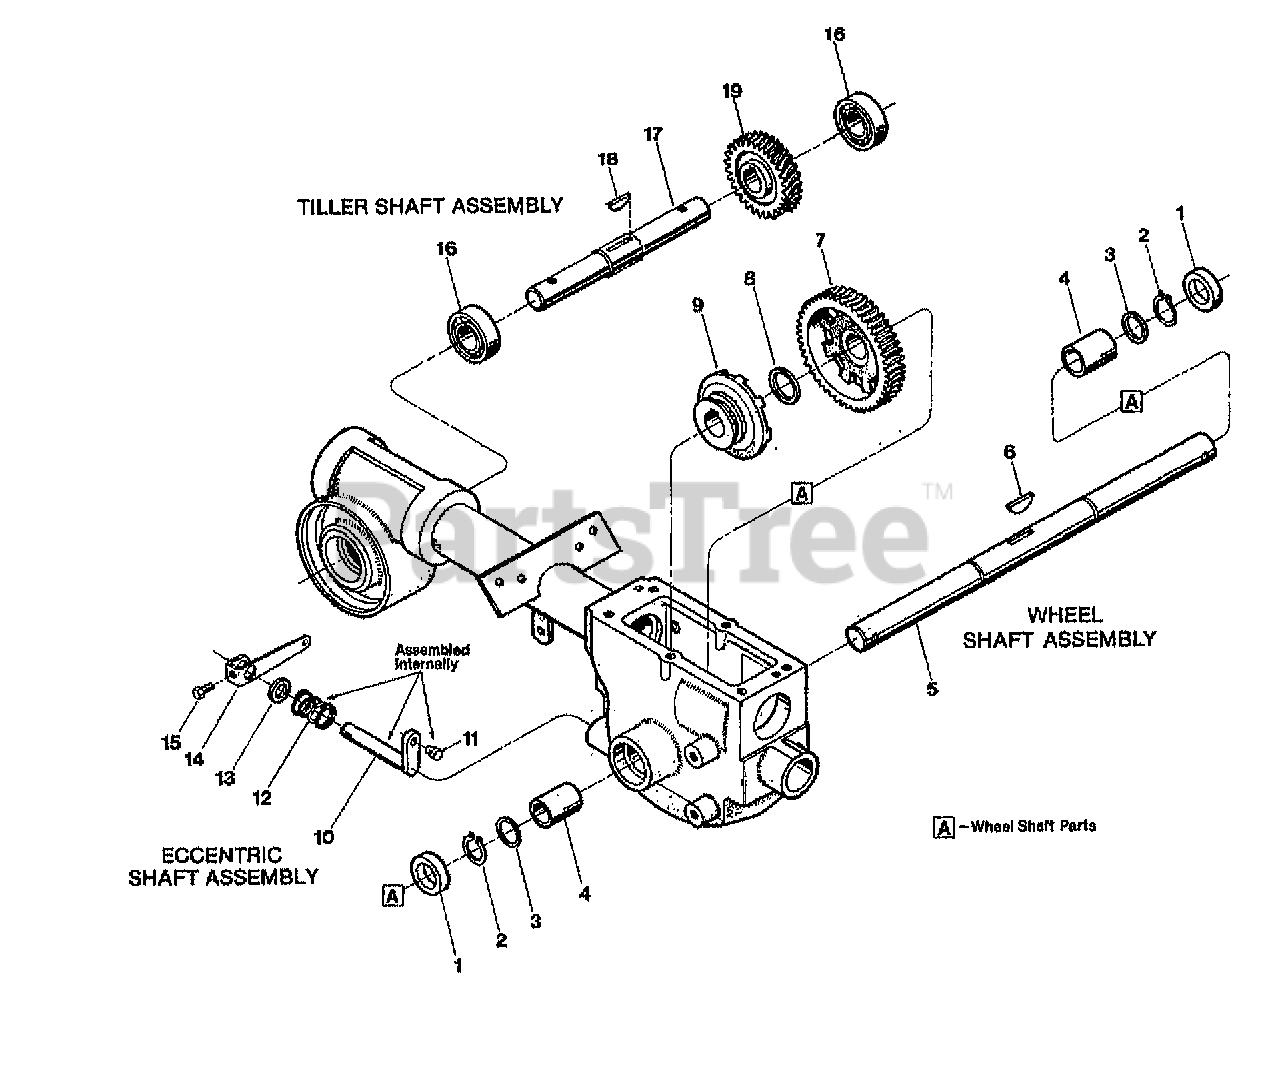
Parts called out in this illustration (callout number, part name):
1	SEAL-OIL WHEELSHAFT
2	RING-HEAVY EXT .906 ID
3	SHIM-1.375X1.015X.062
4	BUSHING-1.25X1.005X1.5
5	WHEELSHAFT W/KEY (AXLE) - (INCL. 6)
6	KEY-HI PRO .25X1.312
7	GEAR-WHEEL DRIVE MACH
8	WASHER-1.468X1.016X.062
9	CLUTCH-MACH
10	WELD-ECCENTRIC
11	PIN-.375 X .72
12	SPRING-.850 X .875 LONG
13	SEAL-OIL ECCENTRIC
14	LEVER-CABLE ADJ PNT
15	SCR-HH 1/4-20X.5 GR5 YEL
16	BEARING-BALL
17	SHAFT-W/KEY (TILLER)
18	KEY-WOODRUFF .25X1.12
19	WORM GEAR - BRONZE, TILLER DRIVE
19	WORM GEAR - BRONZE
